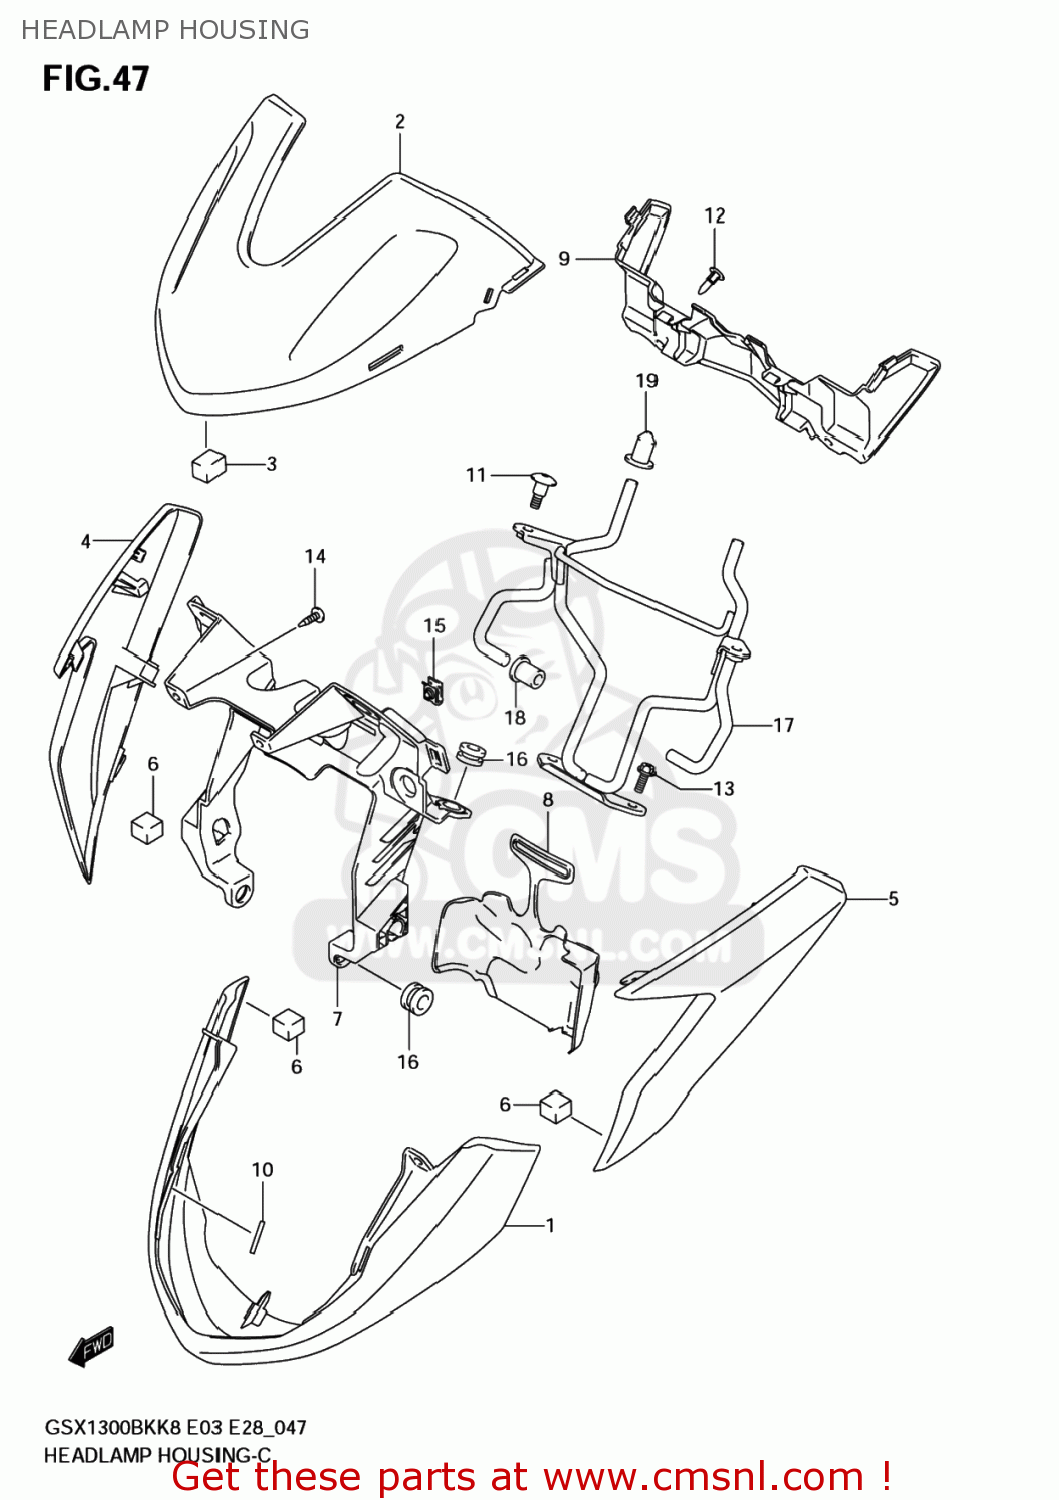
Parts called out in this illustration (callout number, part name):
1	COVER,HEADLAMP LWR
2	COVER,HEADLAMP UPR
3	CUSHION,RR LAMP(17X17X12)
4	COVER,LAMP HOUSING,R(BLACK)
5	COVER,LAMP HOUSING,L(BLACK)
6	CUSHION,RADIATOR COVER INNER
7	COVER,HEADLAMP
8	GROMMET,HEADLAMP HOUSING
9	COVER,HEADLAMP HSG
10	TAPE(6X25X0.13)
11	SCREW(6X20)
12	CLIP(BLACK)
13	BOLT
14	SCREW
15	NUT
16	CUSHION
17	BRACE,HEADLAMP HOUSING
18	CUSHION
19	CUSHION,HEADLAMP HOUSING BRACE
